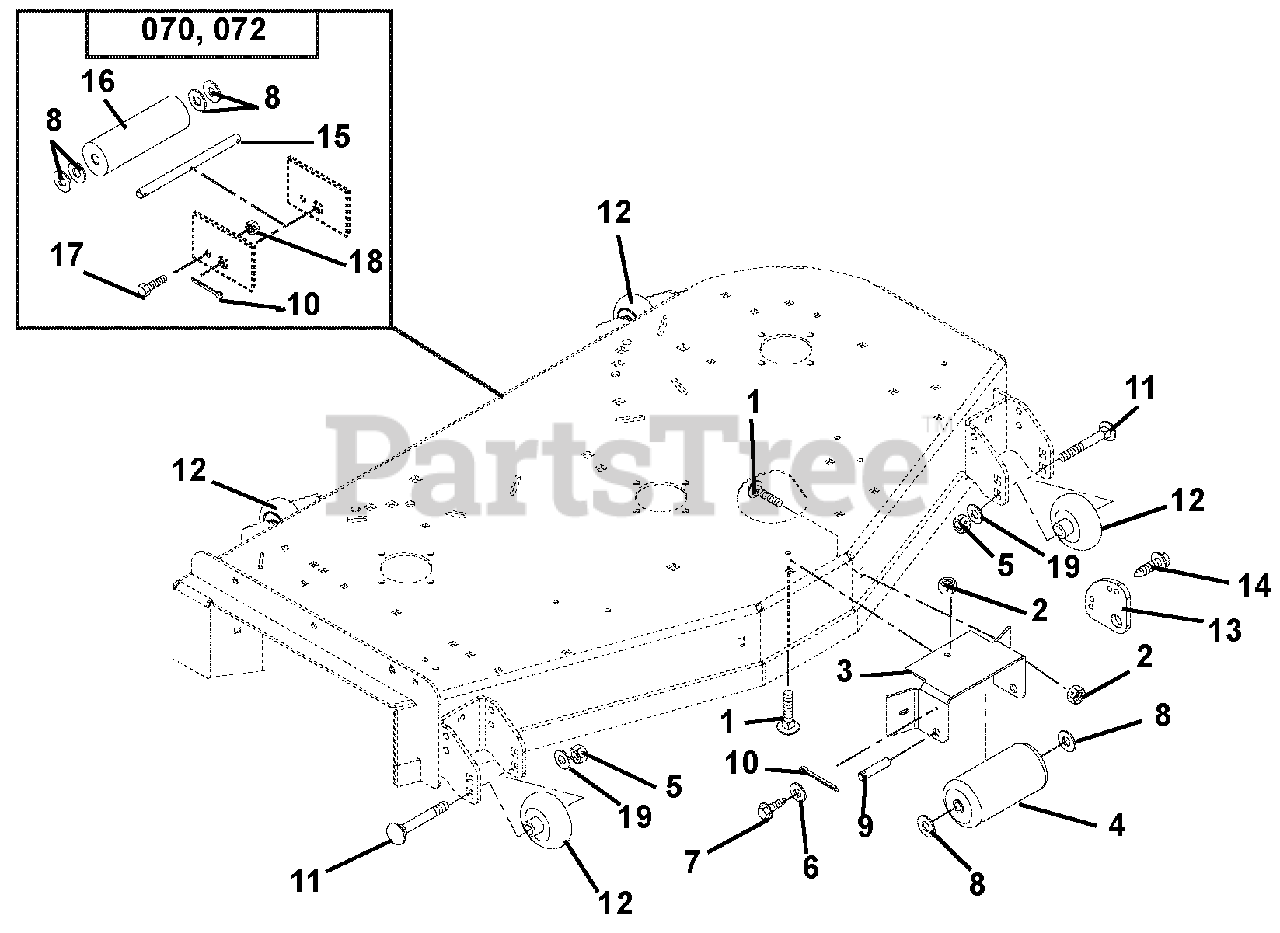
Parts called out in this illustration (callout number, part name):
1	Bolt-Round Head Square Neck .38-16 x 1.00 Grade 5
2	Nut-Locking-Top-Flange .38-16
3	Bracket- Anti-Scalp Roller
5	Nut-Locking-Nylon .50-13
6	Washer-Flat-Steel .281 x .62 x .065
7	Screw-Tapping .25-20 x .75 Hex Washer Head
8	Washer-Flat-Steel .656 x 1.31 x .095 (066, 067 , 068, 069, 071)
10	Pin-Cotter .25 x 2.00 (066, 067 , 068, 069, 072)
11	Bolt-Round Head Square Neck .50-13 x 5.00 Grade 2
12	Wheel, 3 x 5
13	Anti-Scalp Washer
14	Screw-Tapping .25-20 x .62 Hex Washer Head
15	Shift, Center Roller (070, 072)
16	Roller, Gage (070, 072)
17	Bolt-Hex .25-20 x .75 Grade 5 (070, 072)
18	Nut-Locking-Center .25-20 (070, 072)
19	Washer-Flat-Steel .531 x 1.06 x .095
